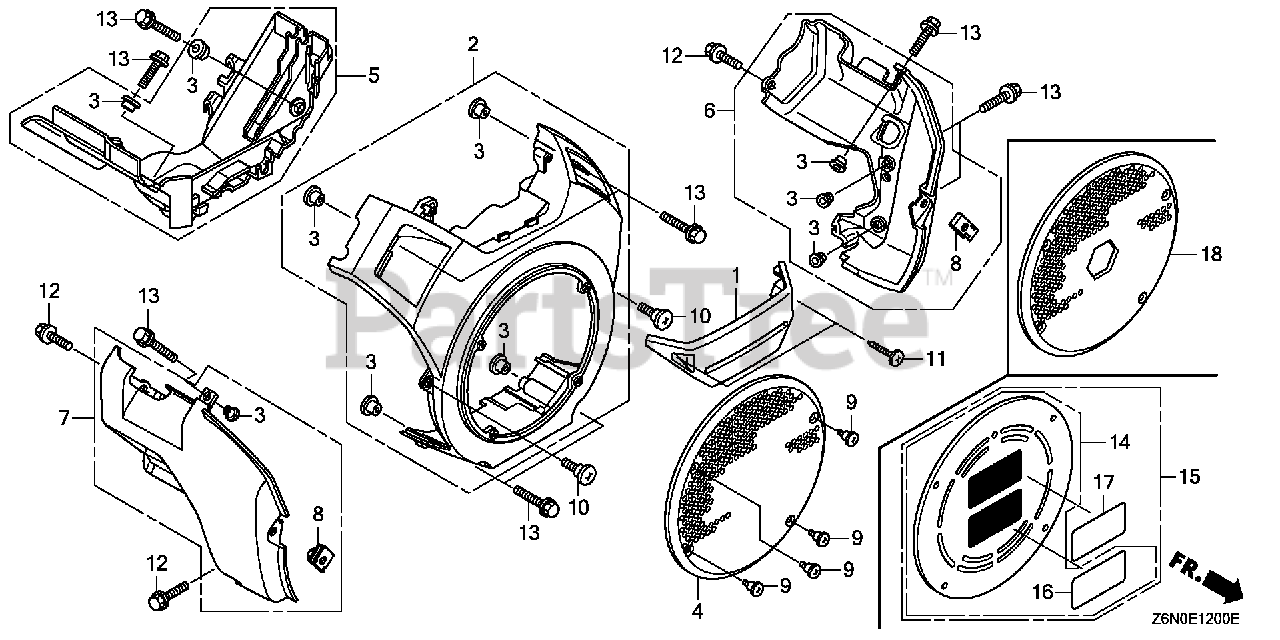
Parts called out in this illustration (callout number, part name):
1	COVER, FUEL PUMP
2	COVER, FAN *R280* (POWER RED)
3	COLLAR, FAN COVER
4	PROTECTOR, FAN COVER
5	SHROUD (UPPER)
6	SHROUD, R. (LOWER)
7	SHROUD, L. (LOWER)
8	NUT, FENDER SETTING
9	SCREW, SPECIAL (4X10)
10	SCREW, SPECIAL (6X15)
11	SCREW, TAPPING (5X20)
12	BOLT, FLANGE (6X16)
13	BOLT, FLANGE (6X20)
